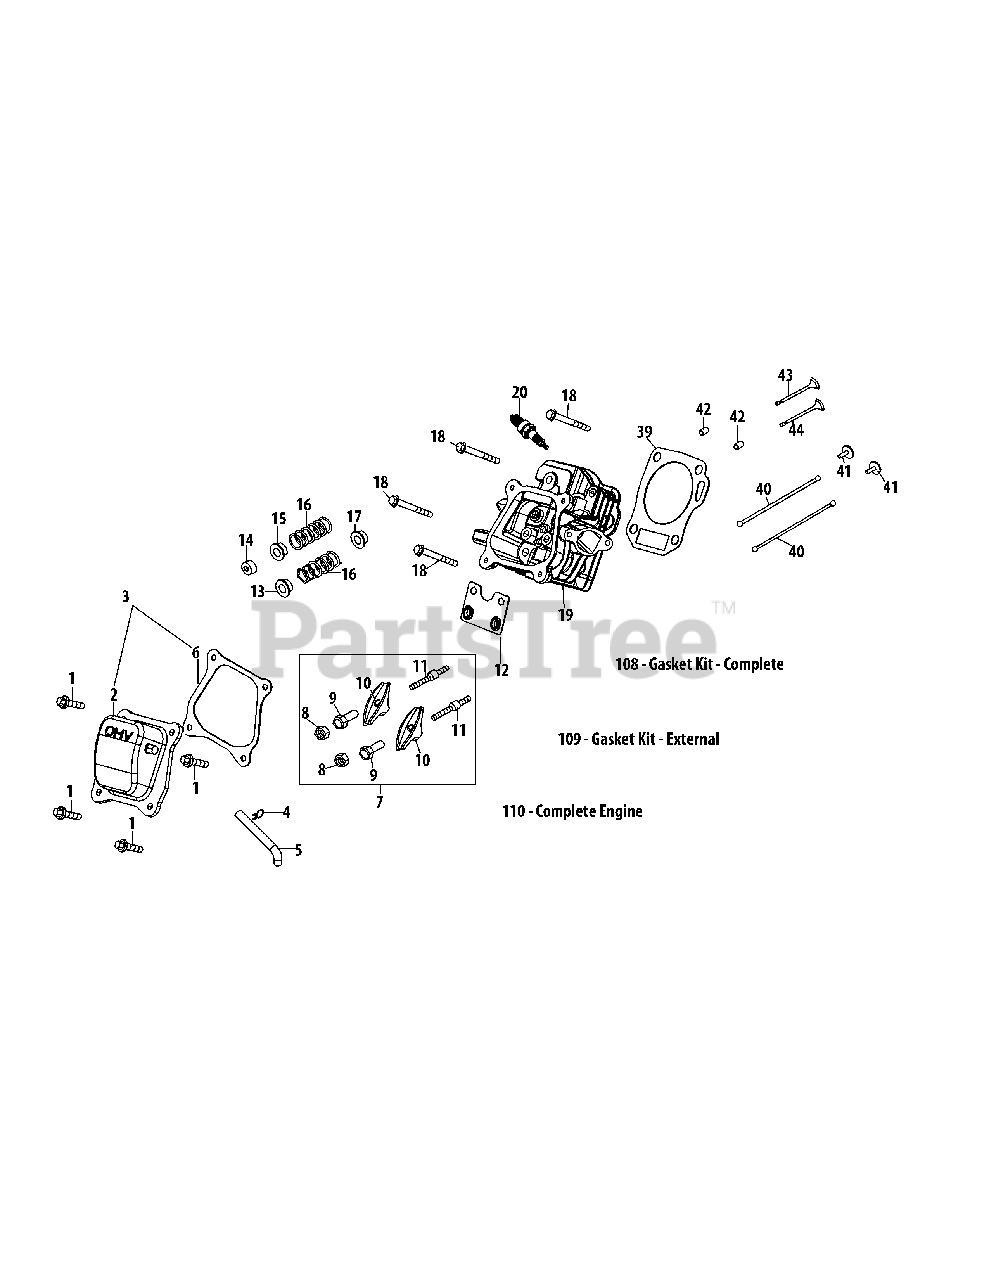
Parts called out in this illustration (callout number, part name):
1	Bolt M6×16
2	Valve Cover
3	Valve Cover Kit
4	Breather Hose Clamp
5	Breather Hose
6	Valve Cover Gasket
7	Rocker Arm Assembly
8	Nut, Pivot Locking
9	Adjusting Nut ,Valve
10	Rocker Arm
11	Bolt, Pivot
12	Push Rod Guide
13	Valve Spring Retainer (Intake)
14	Exhaust Lash Cap
15	Valve Spring Retainer (Exhaust)
16	Valve Spring
17	Valve Seal (Intake)
18	Bolt M8×55
19	Cylinder Head Assembly
20	Spark Plug
39	Gasket, Cylinder Head
40	Push Rod Kit
42	Dowel Pin 10×16
108	Gasket Kit - Complete
109	Gasket Kit - External
110	Complete Engine
